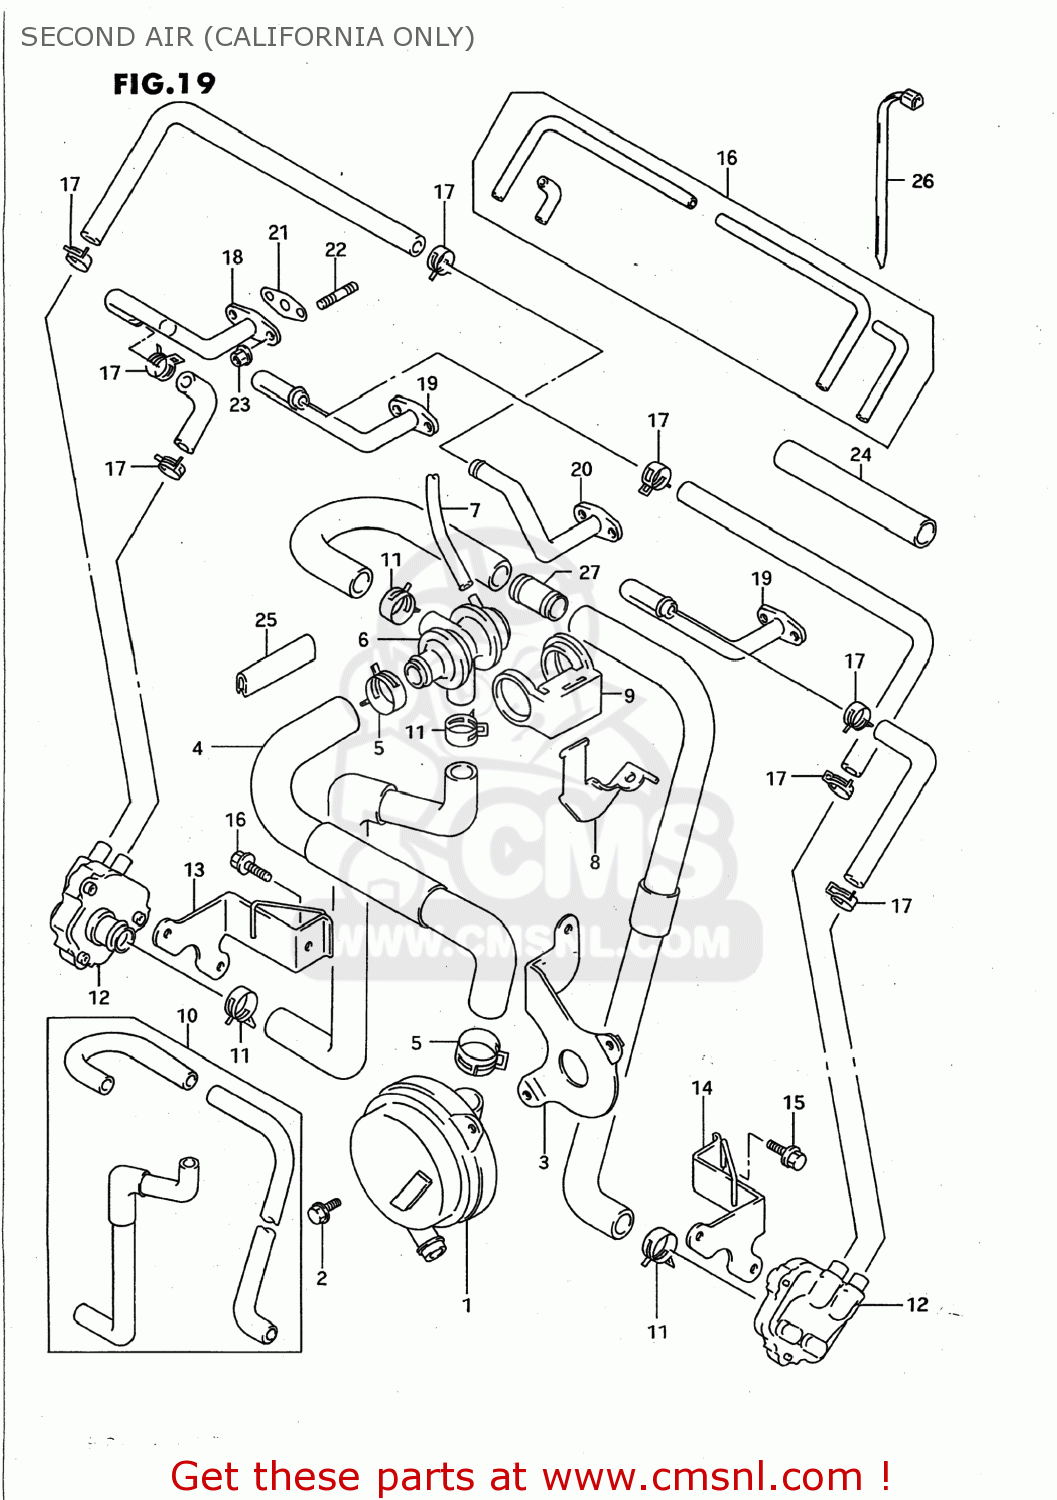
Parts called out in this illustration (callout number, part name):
1	CLEANER ASSEMBLY,SECOND AIR
2	BOLT
3	BRACKET,SECOND CLEANER
4	HOSE,SECOND AIR CLEANER
5	CLAMP
6	VALVE ASSY,2ND AIR SWITCHING
7	HOSE(4.5X8.5X600)
8	BRACKET,SECOND AIR VALVE
9	CUSHION,2ND AIR VALVE
10	HOSE SET,SECOND AIR NO.2
11	CLIP
12	VALVE ASSY,2ND AIR REED
13	BRACKET,REED VALVE,RIGHT
14	BRACKET COMP,REED VALVE
15	BOLT
16	HOSE SET,SECOND AIR NO.1
17	CLIP
18	PIPE,SECOND AIR NO.4
19	PIPE,SECOND AIR NO.4
20	PIPE,SECOND AIR NO.2
21	GASKET,SECOND AIR PIPE (N (NAS)
22	STUD BOLT
23	NUT
24	TUBE,FUEL HOSE
25	MOLDING,FUEL TANK RR
26	CLAMP(L:165)
27	UNION,SECOND AIR VALVE HOSE
